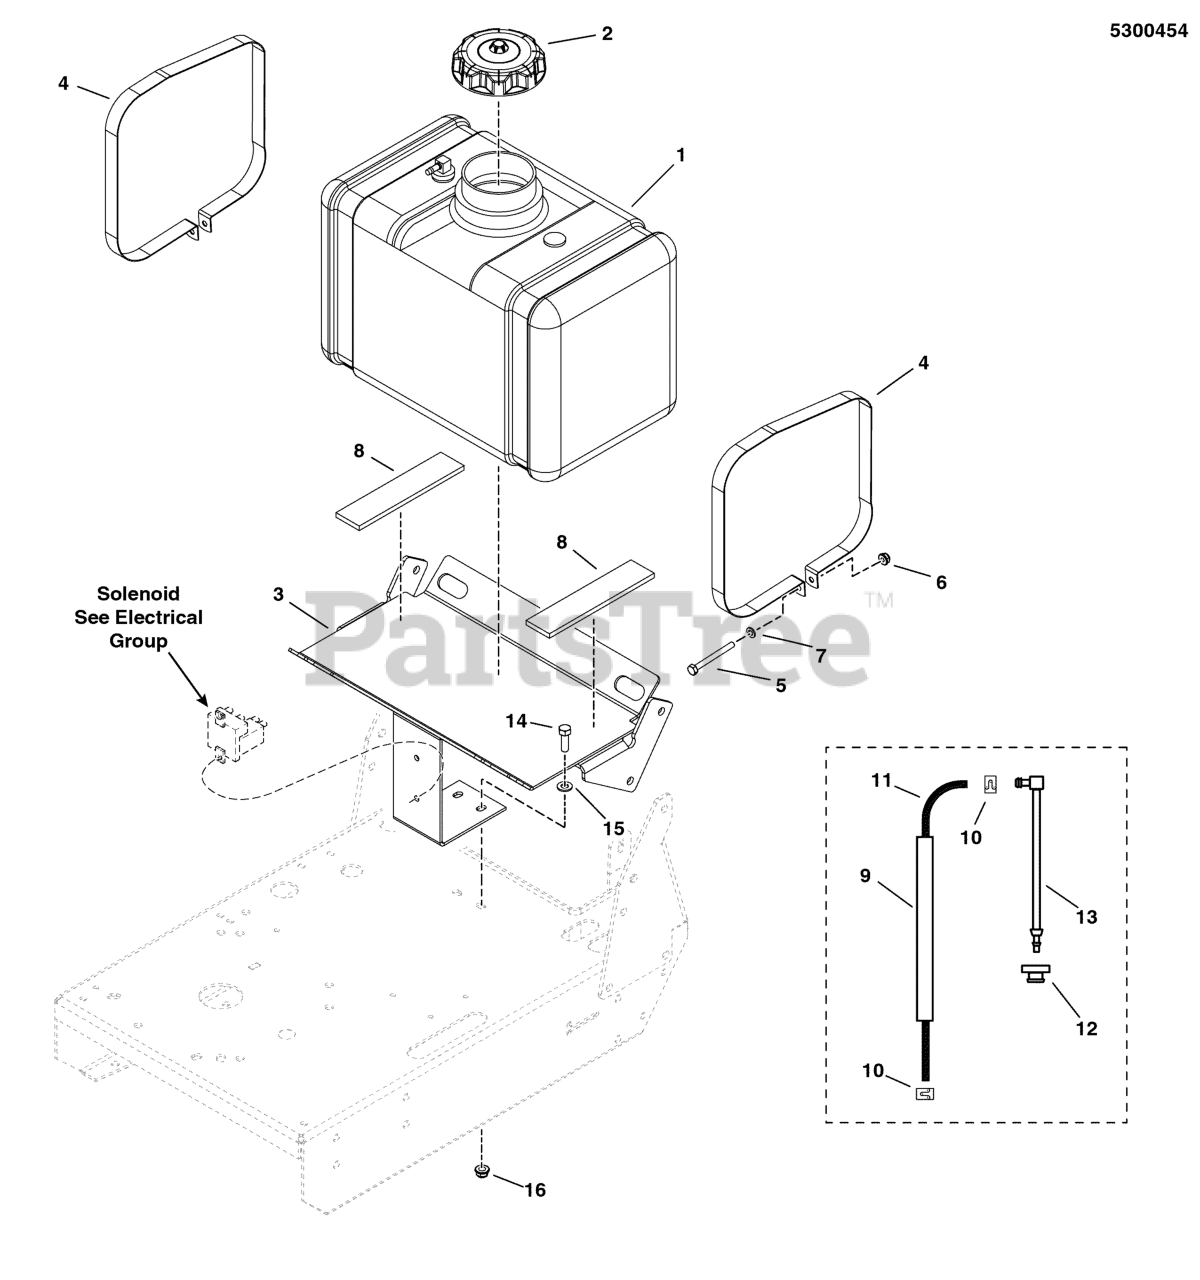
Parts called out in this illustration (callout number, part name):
1	TANK, 5 GAL, W DROP TUBE/VENT
1	TANK, FUEL, PLASTIC, TOP DRAW, NO LOGO
2	FUEL CAP, 3-1/2", MANAGED VENT OUT, 12"
3	WELD, TANK MOUNT, HYDROCUT - RED
4	STRAP, FUEL TANK
5	BOLT, 1/4-20 X 1-1/4 GD5 CZ
6	NUT, 1/4-20 HEX NYLOCK FLANGE
7	WASHER, 1/4 SAE
8	PAD, RUBBER MOUNT
9	WIRE LOOM, 1/2 ID X 20 IN
10	CLAMP, HOSE, EXTERNAL, 1/2 - RED
11	HOSE, 1/4" FUEL, 25.00"
12	BUSHING-FUEL TANK RED RUBBER
13	PICKUP TUBE ASM, FUEL TANK, 8.0"
14	BOLT, 5/16-18 X 1 GD5 YZ
15	WASHER, 5/16" SAE
16	NUT, 5/16-18 HEX NYLOCK FLANGE
17	GROMMET
